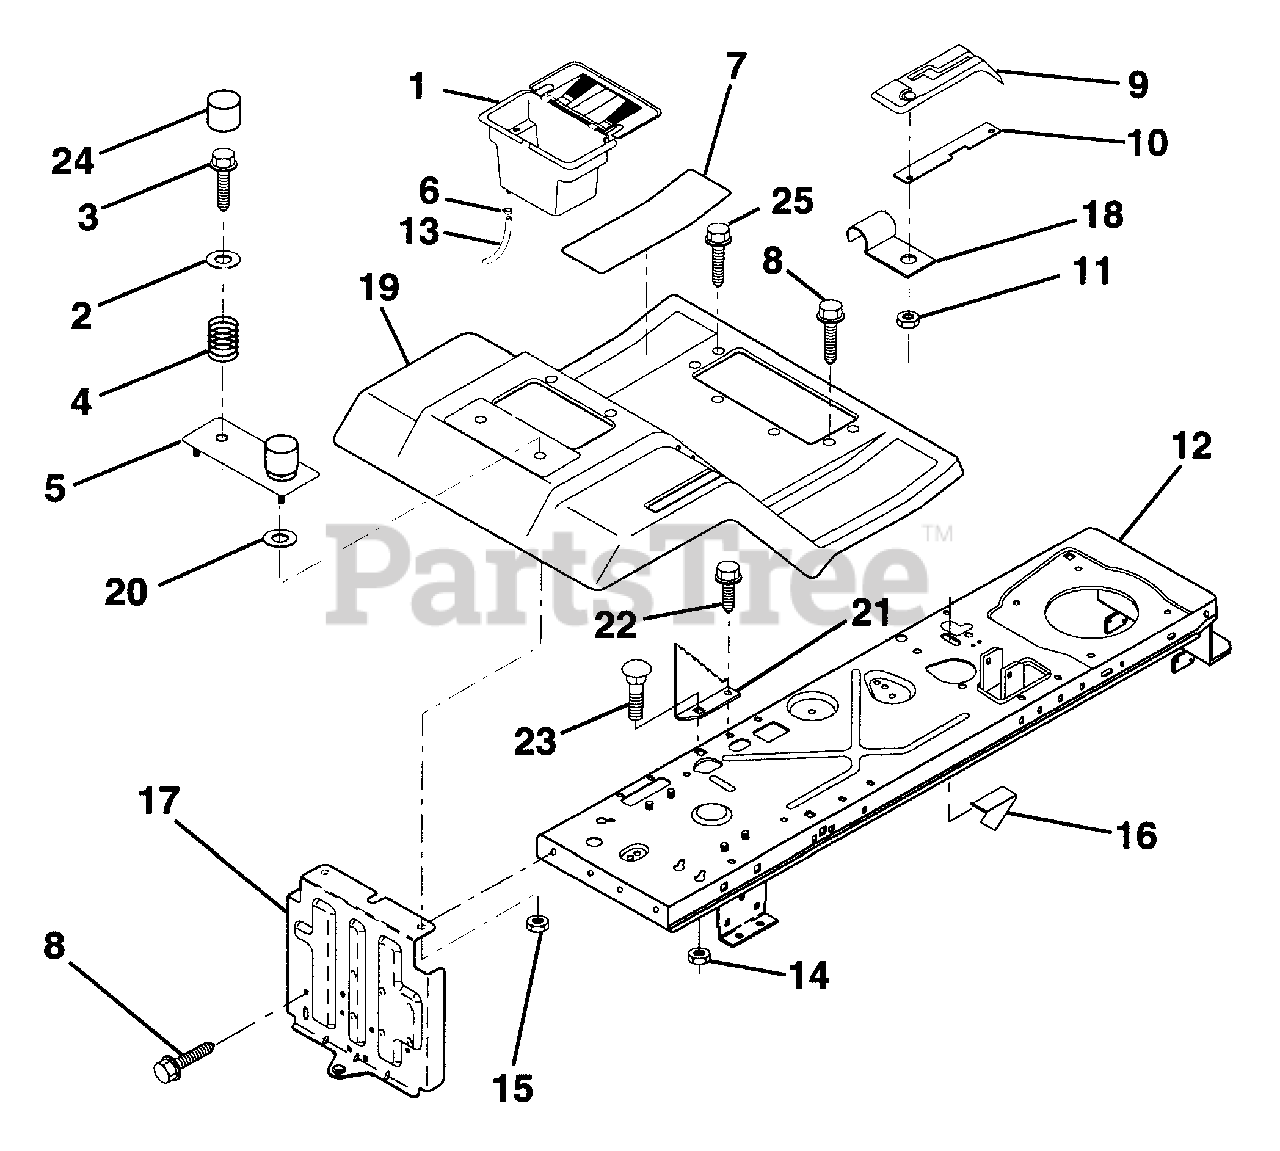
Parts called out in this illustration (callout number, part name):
1	Case Asm. Battery
2	Washer 13/32 x 1-1/4 x 12 Ga.
3	Screw Thdrol. 3/8-16 x 3/4
4	Spring seat
5	Plate Asm. Pnt Battery Fender
6	Clamp Hose Olive
7	Pad Footrest Rubber Deluxe
8	Screw Thdrol. 5/16-18 x 3/4
9	Console Shf. 6sp W/Ign.
10	Plate Lock Shift
11	Nut Self Thd. Wsh-Hd 1/4
12	Chassis Asm. Weldment
13	Tube Plastic
14	Nut Crownlock 5/16-18
15	Nut Keps Blk Hex 1/4-20
16	Switch Actuator
17	Drawbar Asm.
18	Clip Insulated
19	Fend/Foot Asm. Pnt Shf. Fnd.
20	Washer 9/32 x 7/8 x 13 Ga.
21	Bracket Stop Depth
22	Screw Thdrol 5/16-18 x 1/2
23	Bolt Rd hd sqnk. 5/16-18 x 3/4
24	Cap Spring Seat
25	Scr-Hex S.T. 5/16-18 x 1
